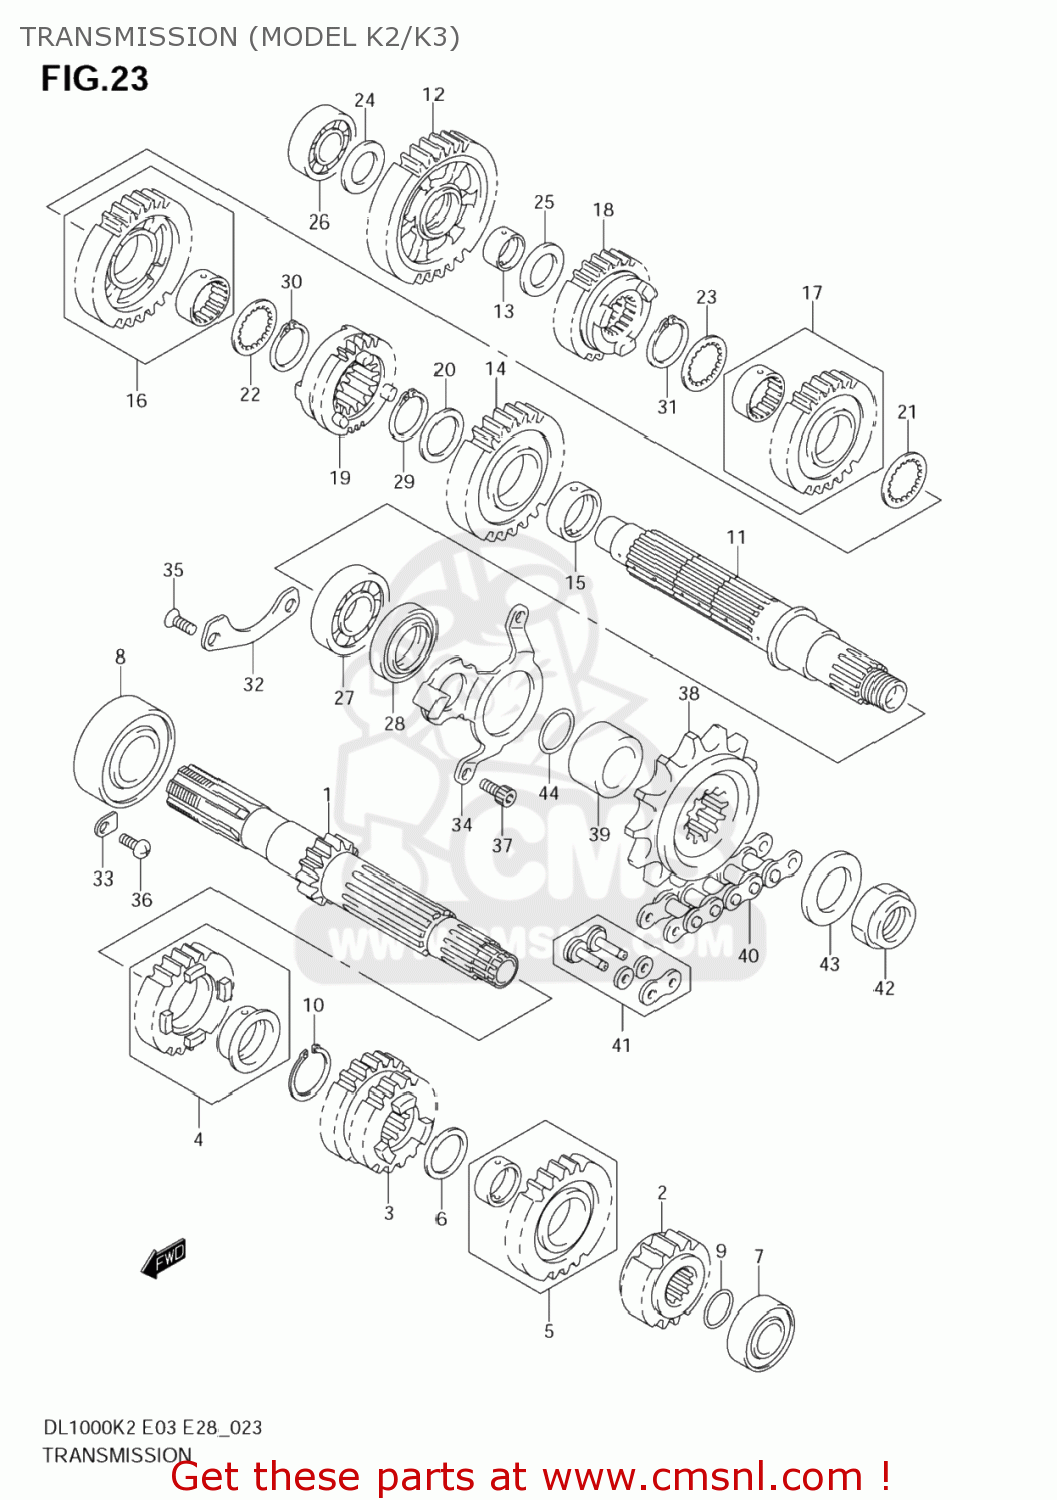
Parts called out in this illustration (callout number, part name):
1	SHAFT,COUNTER (NT:12)
2	GEAR,2ND DRIVE(NT:15)
3	GEAR,3RD & 4TH DRIVE(NT:18/27)
4	GEAR SET,FIFTH DRIVE (NT:
5	GEAR SET, 6TH DRIVE (NT:23)
6	SHIM(22X30X1)
7	BEARING(20X47X14)
8	BEARING(25X62X17)
9	O RING(D:1.9,ID:16.6)
10	CIRCLIP
11	SHAFT,DRIVE
12	GEAR,1ST DRIVEN
13	BUSH
14	GEAR,2ND DRIVEN(NT:29)
15	BUSH,2ND DRIVEN GEAR
16	GEAR SET,THIRD DRIVEN (NT
17	GEAR SET,FOURTH DRIVEN (NT
18	GEAR,5TH DRIVEN(NT:25)
19	GEAR,6TH DRIVEN(NT:21)
20	WASHER(27X36X1)
21	WASHER,LOCK
22	WASHER,3RD & 4TH DRIVEN
23	WASHER,3RD & 4TH DRIVEN
24	SHIM(20X34X1)
25	SHIM(22X34X1)
26	BEARING(20X52X15)
27	BEARING(28X68X20)
28	SEAL,OIL(38X52X8)
29	CIRCLIP
30	CIRCLIP
31	CIRCLIP
32	RETAINER,DRIVE SHAFT BEARING
33	RETAINER
34	RETAINER,DRIVE SHAFT OIL SEAL
35	SCREW(6X12)
36	SCREW
37	BOLT,STRANGER
38	SPROCKET,ENGINE(17T)
39	SPACER,ENGINE SPROCKET
40	CHAIN ASSY (RK525SMOZ7) (GSX-R600K4/K5L:112-110)
41	JOINT SET
42	NUT
43	WASHER(25X41X3)
44	O RING(D:2.4,ID:23.7)
